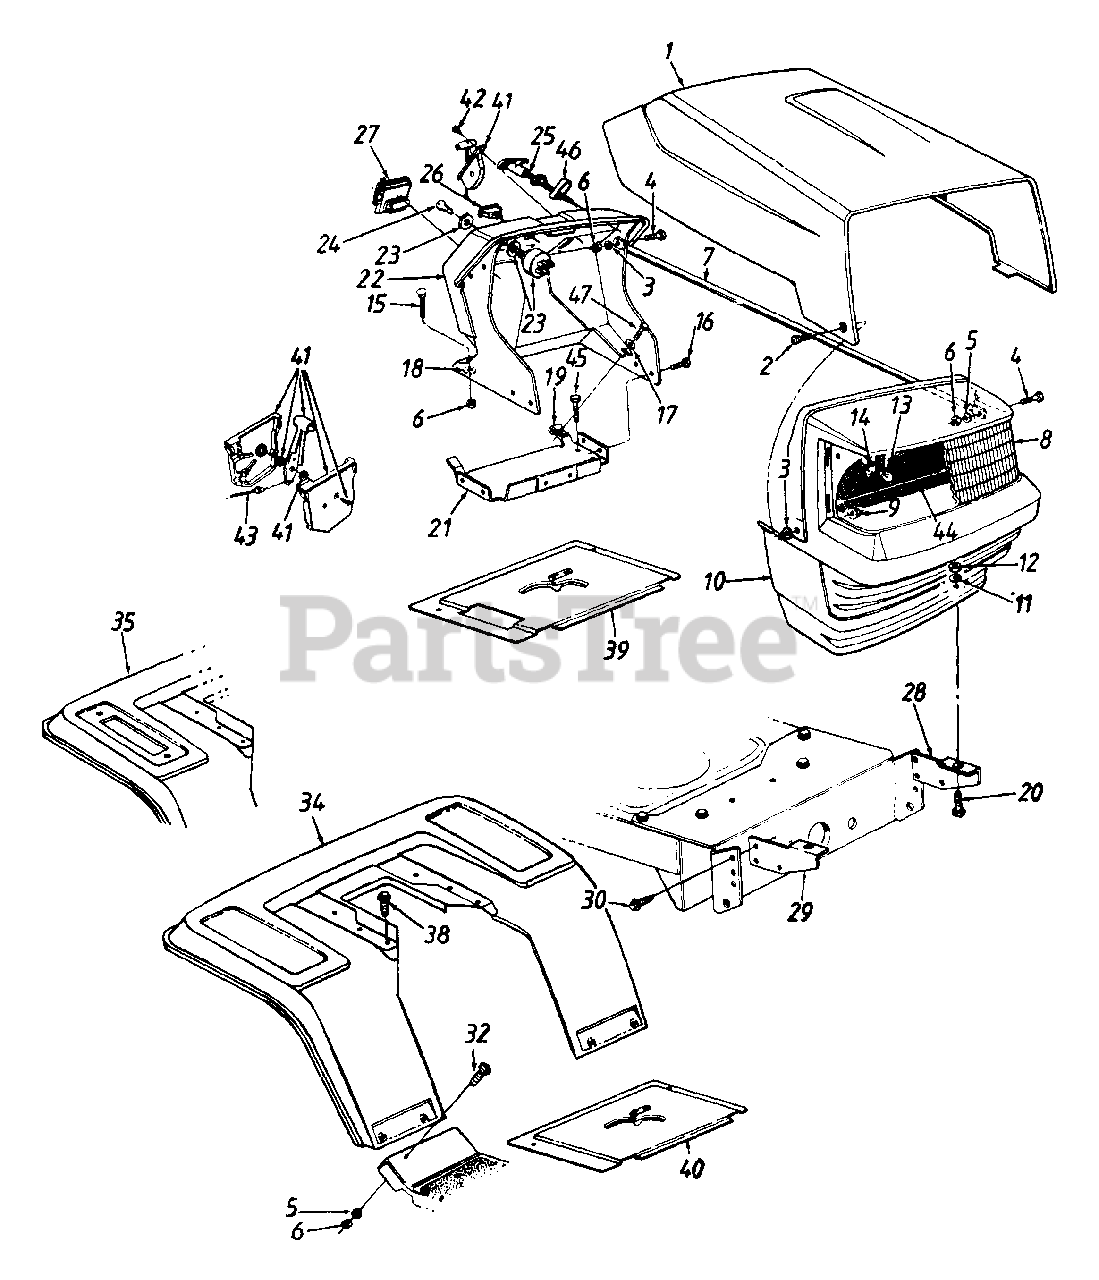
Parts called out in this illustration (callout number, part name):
3	Fl-Wash. .28" I.D. x .75" O.D.
4	Hex Bolt 1/4-20 x .62" Lg."
5	L-Wash. 1/4" I.D.
6	Hex Nut 1/4-20 Thd.
8	Headlight Lens
9	Flange L-Nut 1/4-28 Thd.
10	Grille
11	L-Wash. 5/16" I.D.
12	Hex Nut 5/16-18 Thd.
13	Lamp
14	Socket
15	Carriage Bolt 1/4-20 x .75" Lg.
16	Hex Wash. Hd. TT-Tap Scr. 1/4-20 x .5" Lg.
17	Fl-Wash. .281" I.D. x .73" O.D.
18	Bolt Retainer 1/4" I.D.
19	Speed Nut 1/4-20 Thd.
20	Hex Bolt 5/16-18 x .75" Lg.
21	Gas Tank Support Brkt.
22	Dash w/Ammeter Hole
23	Ignition Switch
24	Ignition Key
25	Choke Control
26	Light Switch
27	Ammeter
28	Grille Mtg. Brkt. - L.H.
32	Truss Mach. Scr. 1/4-20 x .5" Lg.
38	Hex Wash. Hd. AB-Tap Scr. 5/16 x .75" Lg.
39	Shift Cover w/ Cutout
40	Shift Cover
41	Throttle Box Ass'y.
42	Truss Mach. AB-Tap Scr. #10 x .5" Lg.
43	Throttle Control Wire
44	Grille Reflector Label
45	Hex Wash. Hd. B-Tap Scr. 5/16-18 x .5" Lg.
46	Choke Retainer
47	Hex TT-Tap Scr. 1/4-20 x .75" Lg.
